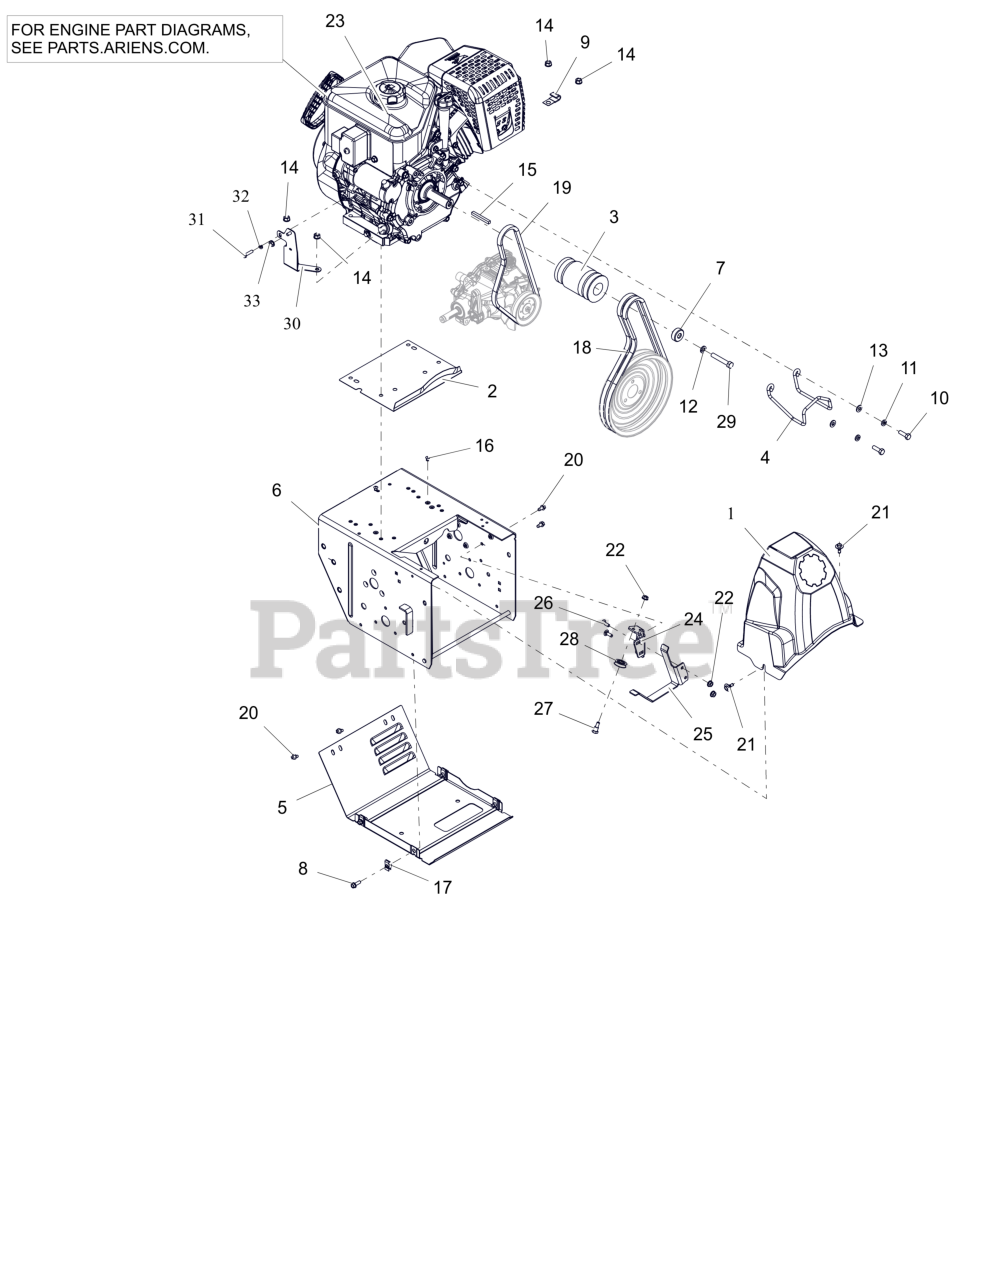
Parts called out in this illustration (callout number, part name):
1	COVER, BELT
2	BAFFLE, WATER - LARGE BLOCK
3	SHEAVE, COMBO HYDRO WHEEL 4L
4	FINGER, BELT
5	COVER, BOTTOM - VENTILATED
6	FRAME, MAIN - PRO (WELDMENT)
7	BSHG, SPCR .406 X 1.250 X .500
8	BLT, HWH .25-20X.75 G5 ZCC
9	J-CLAMP
10	BLT, HEX 0.3125-24X1 G5 ZCC
11	WSHR, LK-HVY .312X.097 ZCC
12	WSHR,LK-REG .375X.094 ZCC
13	WSHR,FLT .344X.688X.065 ZCC
14	NUT,LK-CTR-FLG .31-18 GF ZCC
15	KEY .25X.25X2.25
16	RVT, POP .1875 ZCC
17	NUT-RTNR .25-20X.56
18	V-BELT, HA-RAW EDGE (SET)
19	V-BELT, 4L-WRAPPED
20	SCR-TAP .25-20X.50 HWH ZCC
21	SCR-TAP .25-20X.5 CAPTIVE
22	NUT-LK-TOP-FLG .250-20 GF ZCC
23	ENGINE,EFI420 GEN3 120V/60W
24	BRACKET, CLUTCH CABLE
25	FINGER, BELT - FLAT
26	BLT, RHSN .25-20X.750 G5 ZCC
27	BOLT, SHLDR -.375 X .375 X .25-20
28	PULLEY, CABLE
29	BLT, HEX .38-24X2.25 G5 ZCC
30	WLDMT- LG BLOCK FUSE MOUNT
31	BLT,HEX M6-1X25 G8.8 ZC120
32	WSHR,LK-REG .250X.062 ZCC
33	NUT-LK-CTR-FLG .25-20 ZC120
